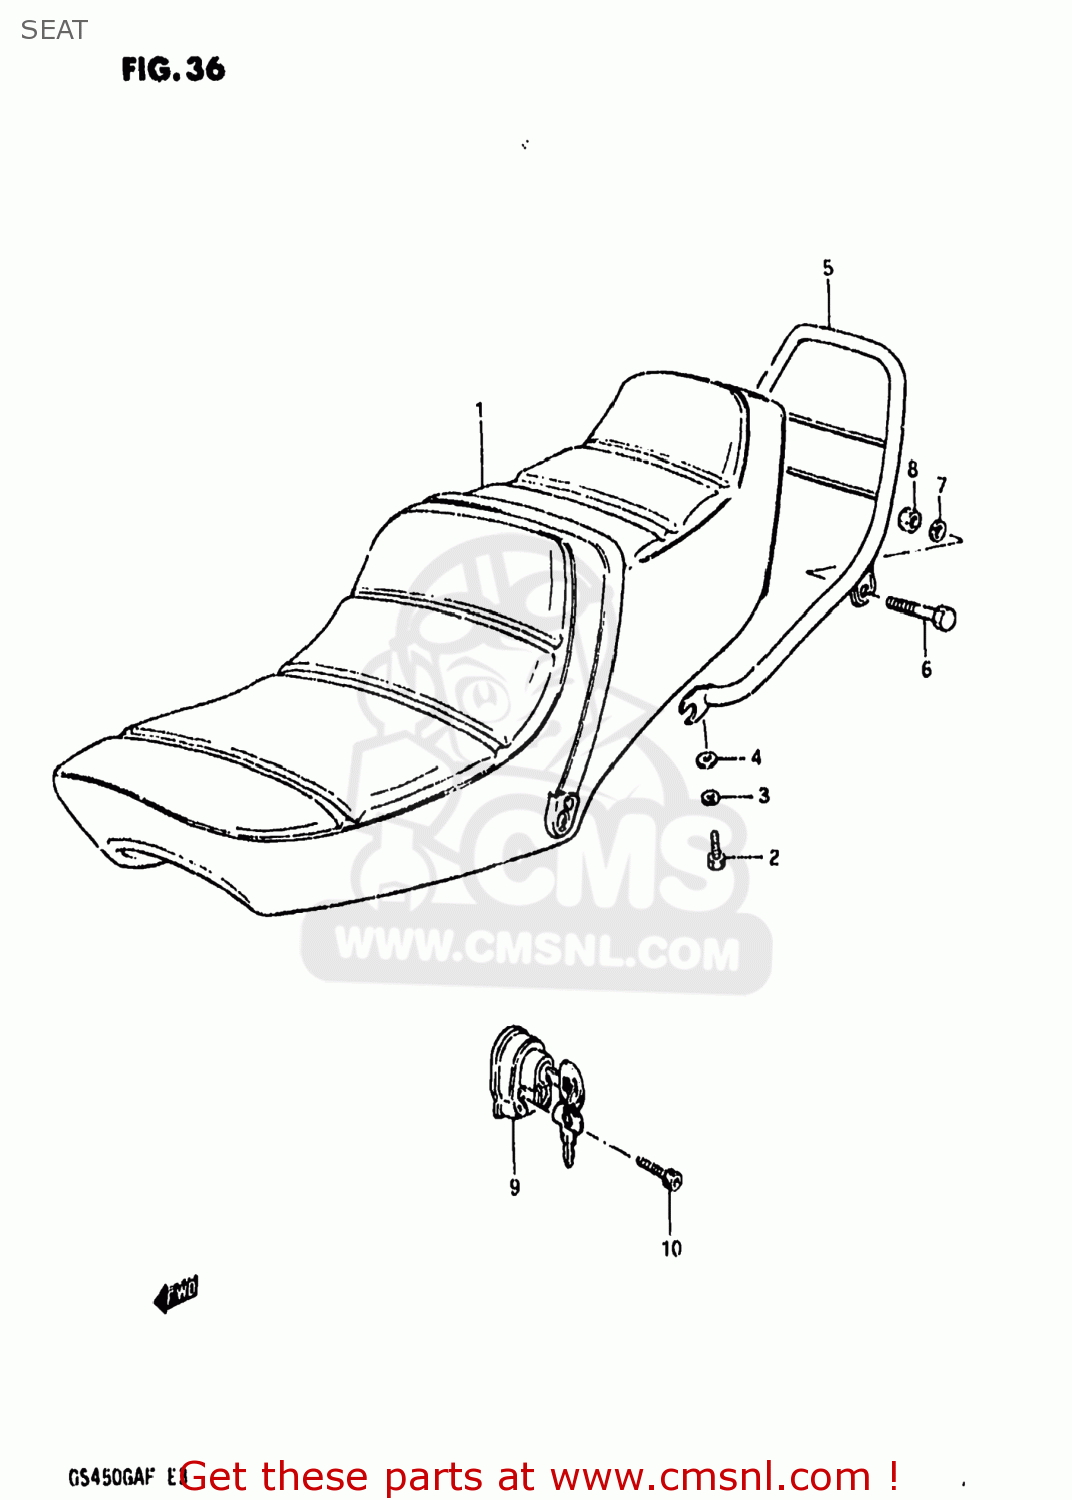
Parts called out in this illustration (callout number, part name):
1	SEAT ASSEMBLY
2	BOLT(6X20)
3	LOCK WASHER
4	WASHER
5	HANDLE,PILLION RIDER
6	BOLT
7	LOCK WASHER
8	NUT
9	LOCK ASSY,HELMET
10	BOLT 5X25
